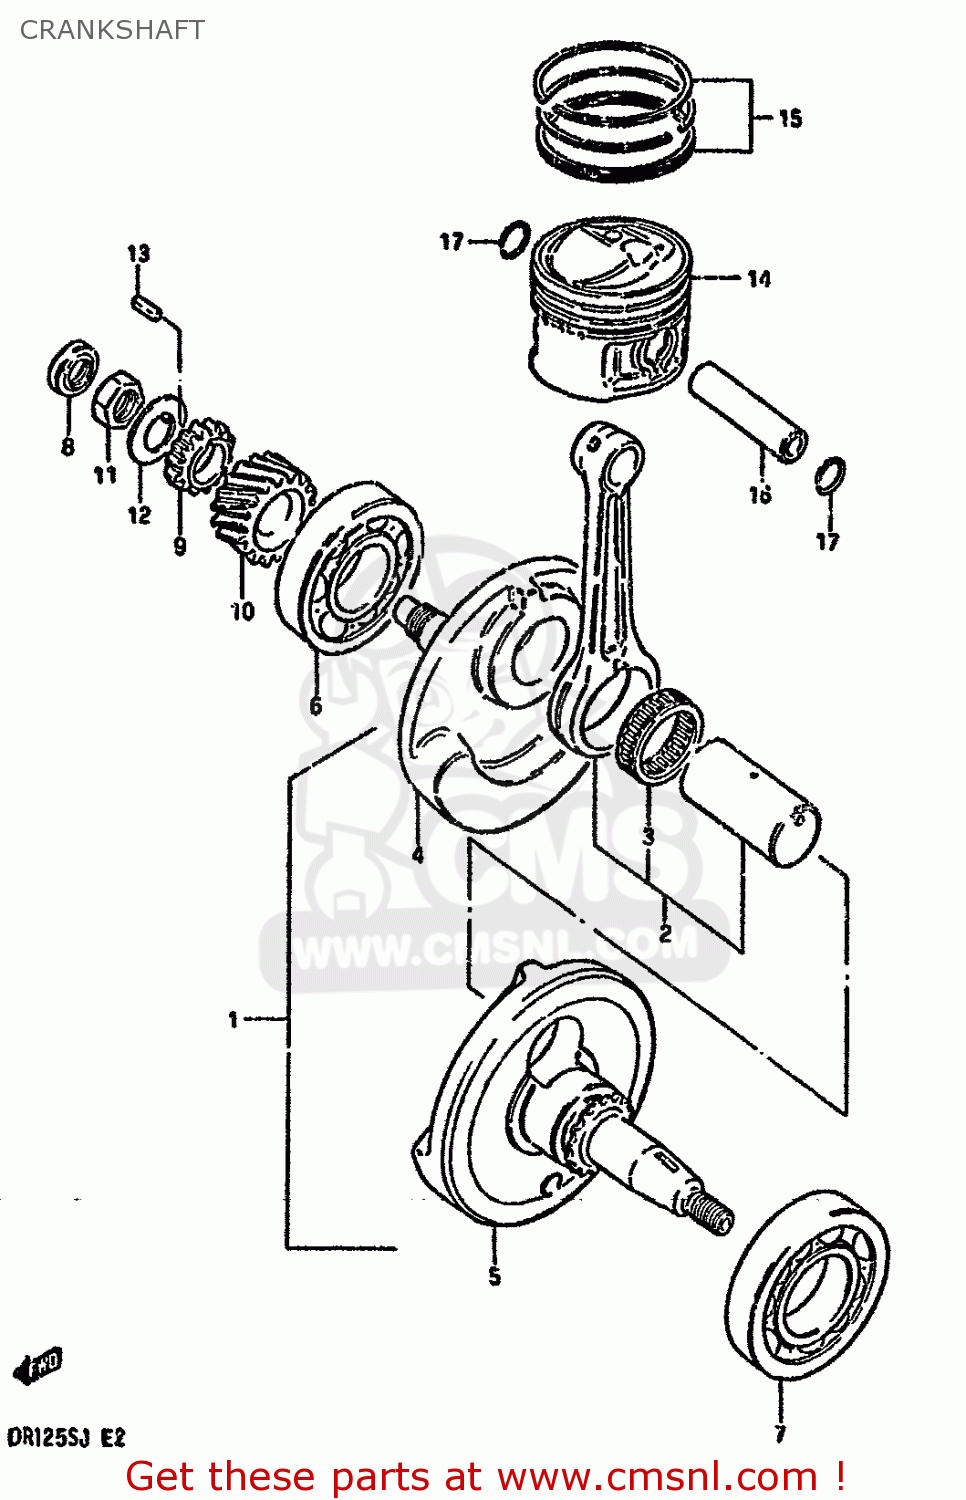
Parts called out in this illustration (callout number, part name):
1	CRANKSHAFT ASSEMBLY
2	CRANKSHAFT ASSEMBLY
3	BEARING
4	CRANKSHAFT
5	CRANKSHAFT,LEFT
6	BEARING(28X68X18)
7	BEARING(35X72X17)
8	OIL SEAL
9	GEAR,OIL PUMP DRIVE
10	GEAR,PRIMARY DRIVE
11	NUT
12	WASHER
13	KEY
14	PISTON (STD)
15	RING SET,PISTON
16	PIN,PISTON
17	RING,SNAP 14MM
